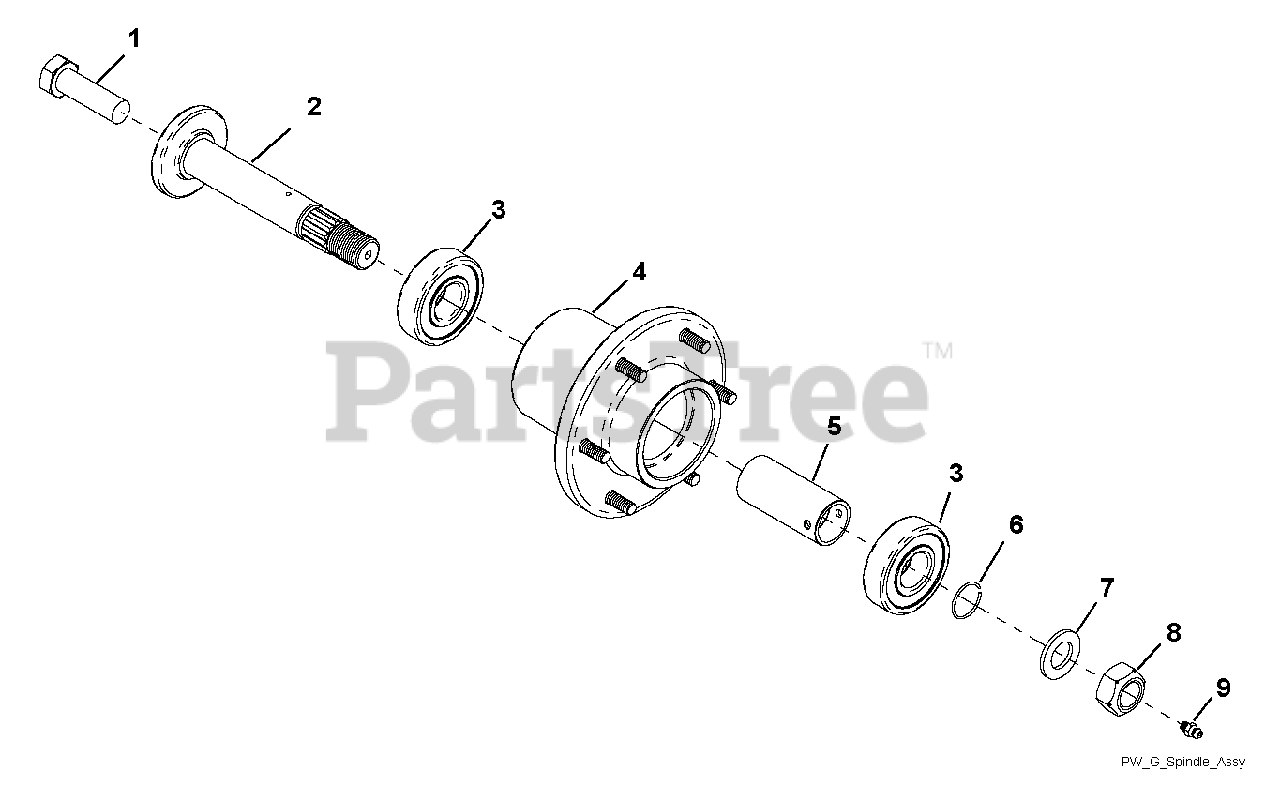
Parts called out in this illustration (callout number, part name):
1	BOLT, 5/8-11 X 2.00 HEX 8 Y
2	SHAFT, SPINDLE 3/4-16
3	BEARING, 6305LLC
4	HOUSING, SPINDLE W/STUDS
5	SPACER, 1.250X1.000X2.780
6	RING RETAINER S/O
7	WASHER, .75X1.3125X.120
8	LOCKNUT, 3/4-16 CROWN PL
9	FTG, 1/4-28 STRGT GREASE ZERK
